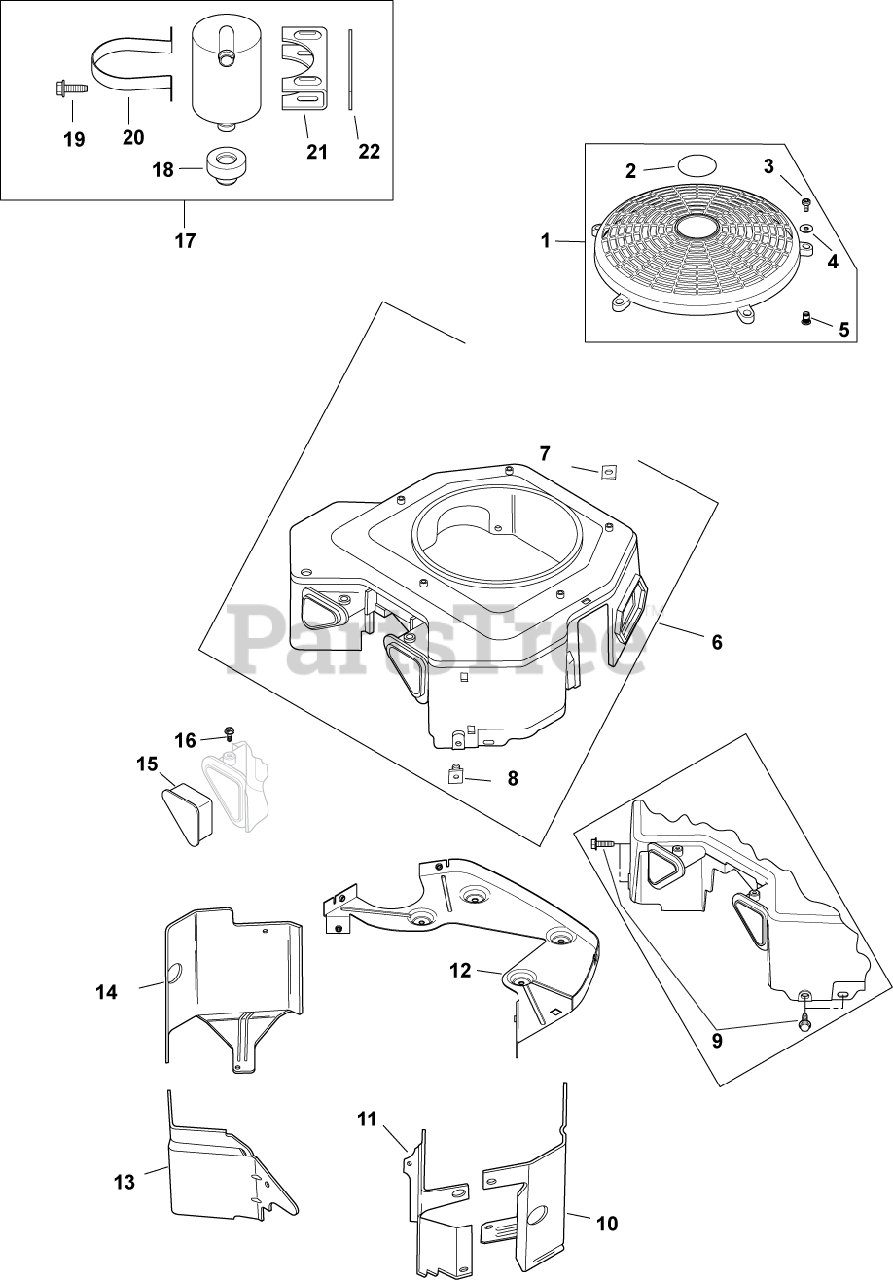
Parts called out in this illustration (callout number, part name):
1	KIT, FIXED GUARD
2	DECAL, GRASS SCREEN USE 24 113 499-S
3	SCREW, SEMS
4	WASHER, FLAT 7/32"
5	INSERT, THREADED USE 25 332 19-S
6	KIT, BLOWER HOUSING
7	NUT, PLASTIC - BLACK
8	NUT, PLASTIC
9	SCREW,FLG THD FRM M6X1.0X16-(#25086397S)
10	BAFFLE,VALLEY #2SIDE(KM)-USE 24 063 88-S
11	BAFFLE,VALLEY #2CYLINDER-USE 24 063 94-S
12	PLATE, BACKING-USE 24 146 59-S
13	BAFFLE,VALLEY #1CYLINDER-USE 24 063 93-S
14	CYL BARREL #1 SIDE
15	COVER, BLOWER HOUSING USE 24 096 160-S
16	SCREW, WSH HD TAP #8-18X1/2"
17	KIT, BREATHR SEPARATR-(#24755241S)
18	GROMMET, RUBBER
19	SCREW,FLG THD FRM M5X0.8X16-(#25086398S)
20	STRAP, BREATHER - USE 24 755 241-S
21	BRACKET, BREATHER SEPARATOR
22	SPACER
